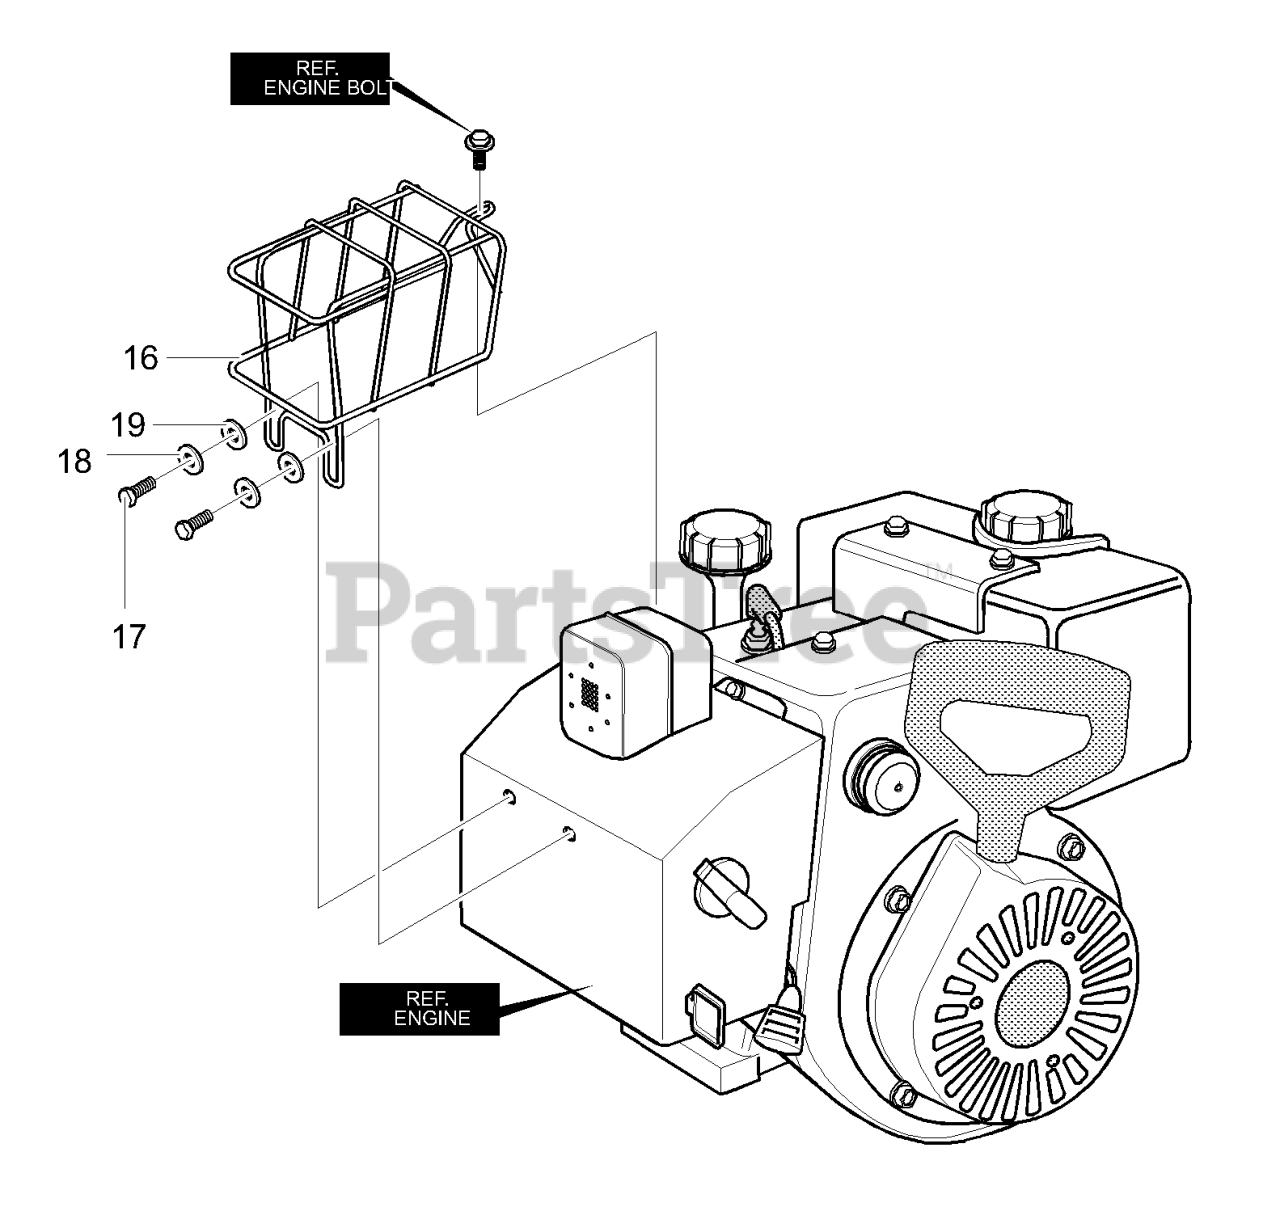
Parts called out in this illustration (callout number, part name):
16	GUARD, MUFFLER
17	SCREW, #10 x .75
18	WASHER
19	WASHER
